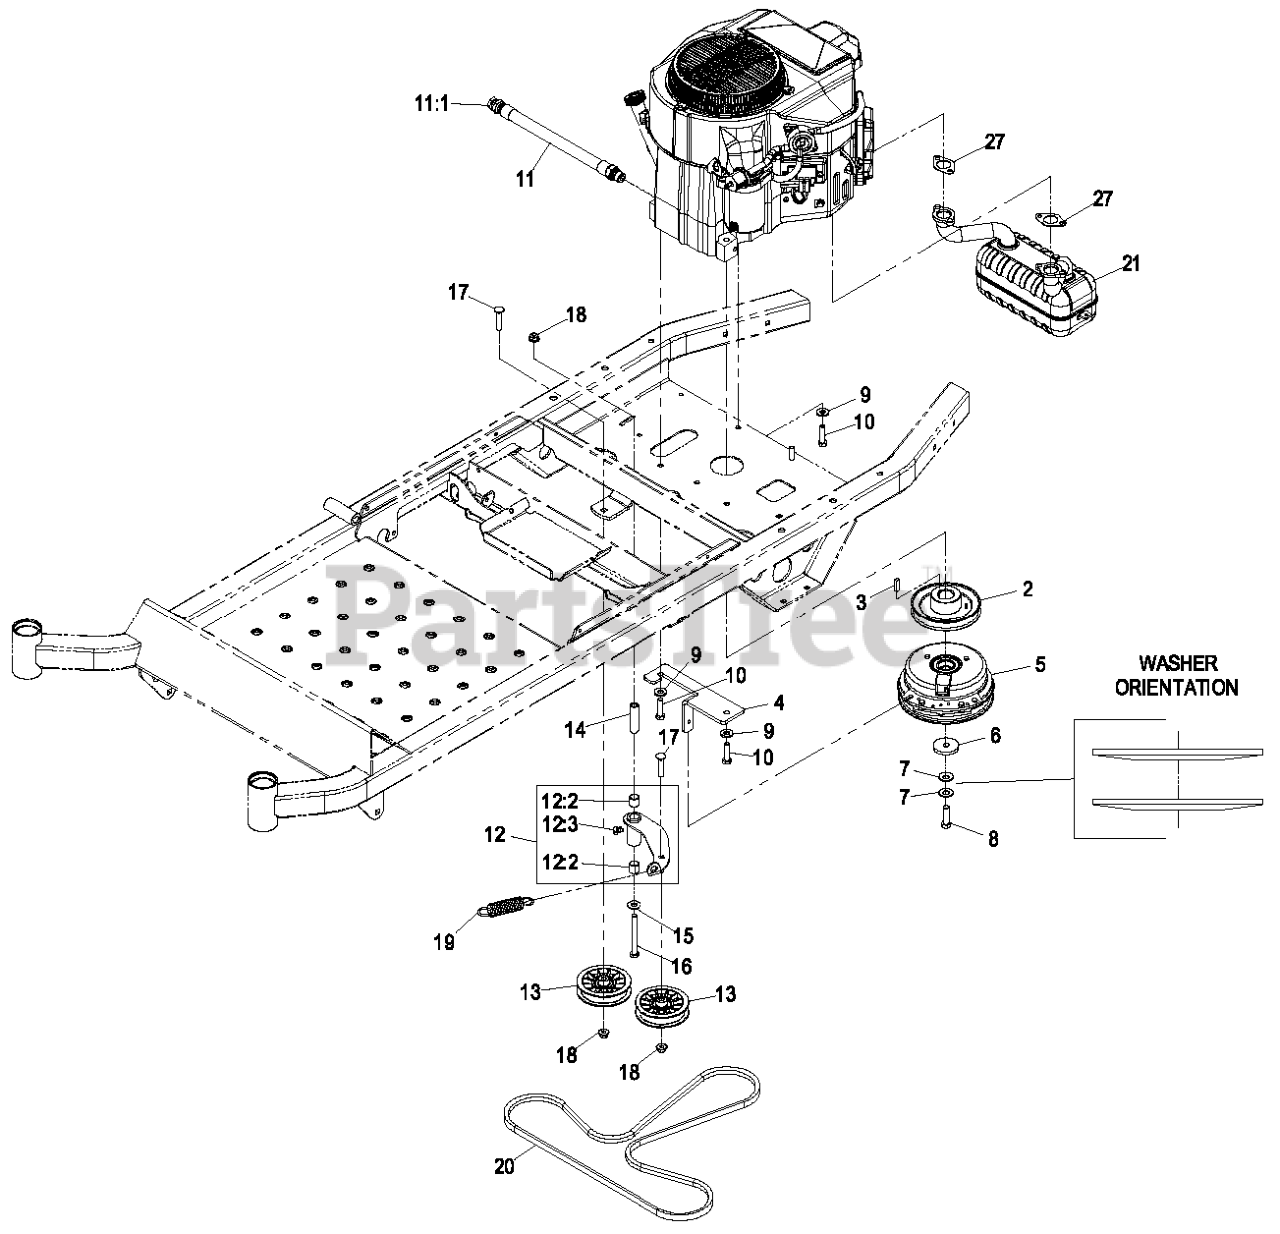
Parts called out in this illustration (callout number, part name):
2	SHEAVE-PUMP, DRIVE
4	ANCHOR,CLUTCH
6	WASHER-CLUTCH
7	WASHER-SPRING
8	SCREW-HH 7/16-20 X 1 1/2 W/LOCTITE
9	WASHER-BELLEVILLE
10	SCREW-HH
12	ASM,IDLER ARM
12:2	SLEEVE-BEARING
12:3	FITTING-GREASE, 90 DEG
13	PULLEY-FLAT IDLER
14	BUSHING-PIVOT, IDLER
15	WASHER-FLAT
16	SCREW-CARR
17	SCREW-CARR
18	NUT-HF, NI
19	SPRING-EXTENSION
20	V-BELT
21	MUFFLER-KAWASAKI
27	GASKET-EXHAUST
